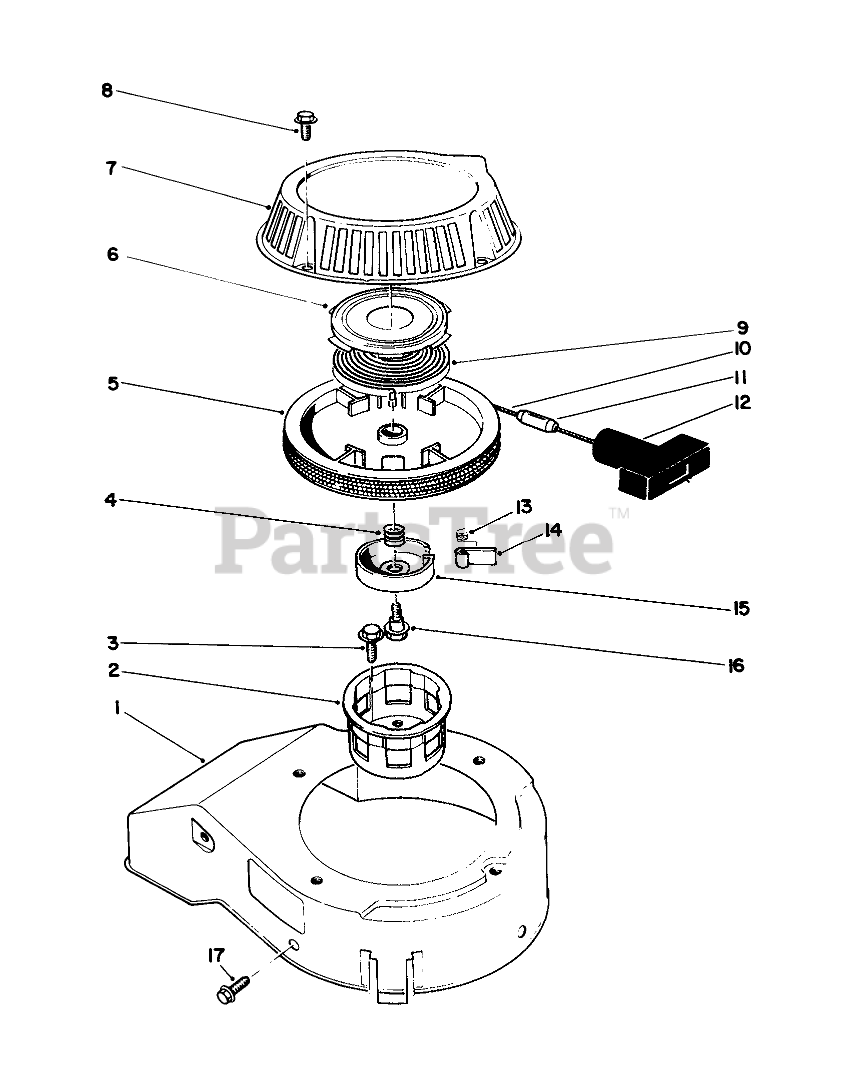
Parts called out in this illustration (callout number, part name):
1	COVER
2	CUP - STARTER
4	SPRING
6	Retainer-Recoil Spring
8	SCREW-HHF
9	Spring-Recoil
10	ROPE-STARTER
12	HANDLE-RECOIL
13	SPRING
15	RETAINER
